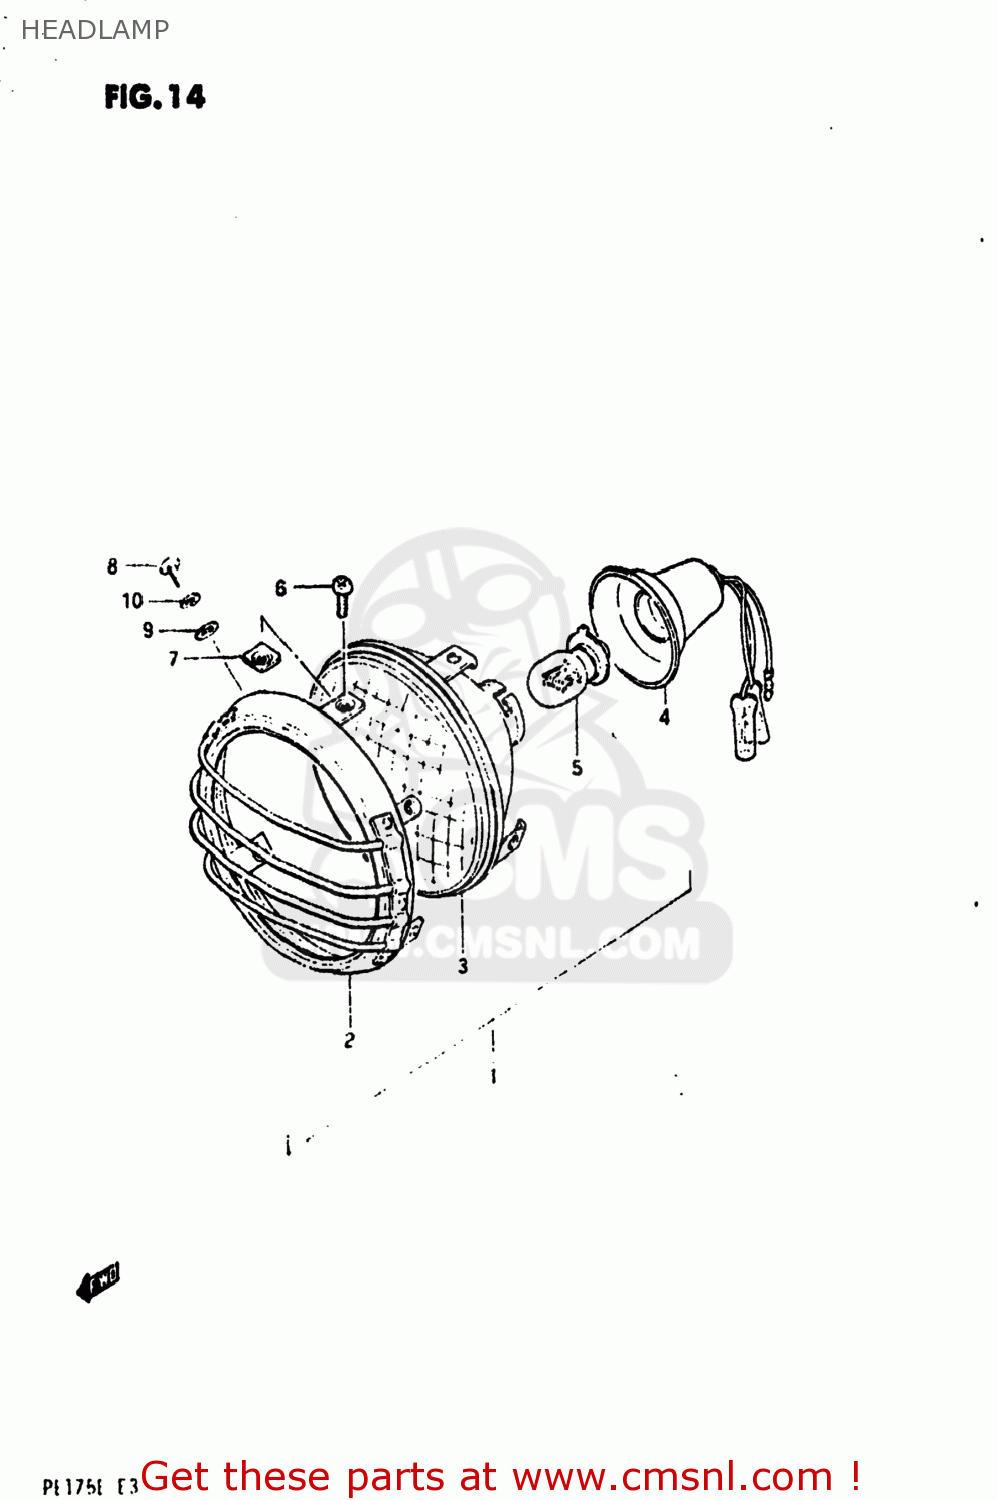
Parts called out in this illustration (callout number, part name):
1	LAMP ASSEMBLY,HEAD
2	RIM,HEADLAMP
3	LAMP UNIT
4	SOCKET,HEADLAMP
5	BULB(6V15/15W/STANLEY,A3598HA)
6	SCREW
7	NUT
8	SCREW
9	WASHER
10	LOCK WASHER
